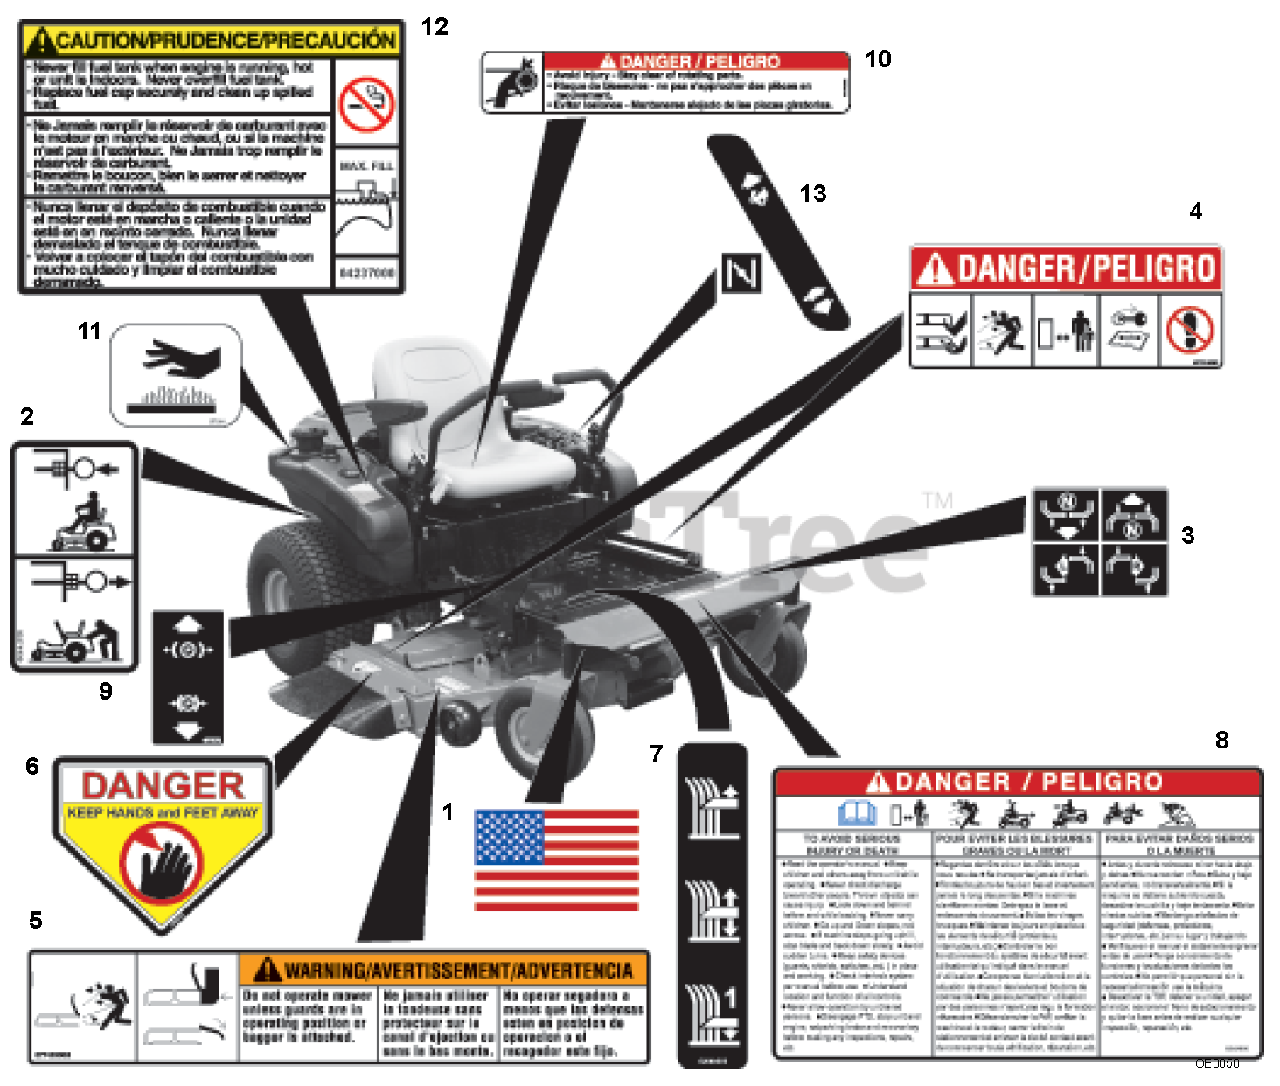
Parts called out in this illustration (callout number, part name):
1	DECAL, AMERICAN FLAG
2	DECAL, TRANSMISSION DISCONNECT
3	DECAL, INSTRUCTIONAL-STEERING
4	DECAL, MOWER PAN DANGER
5	DECAL, WARNING
6	DECAL, DANGER
7	DECAL, CUT HEIGHT
8	DECAL, DANGER BILINGUAL
9	DECAL, PARKING BRAKE LEVER
10	DECAL- DANGER
11	DECAL, HOT SURFACE
12	DECAL,FUEL WARNING
13	DECAL, SPEED CONTROL
